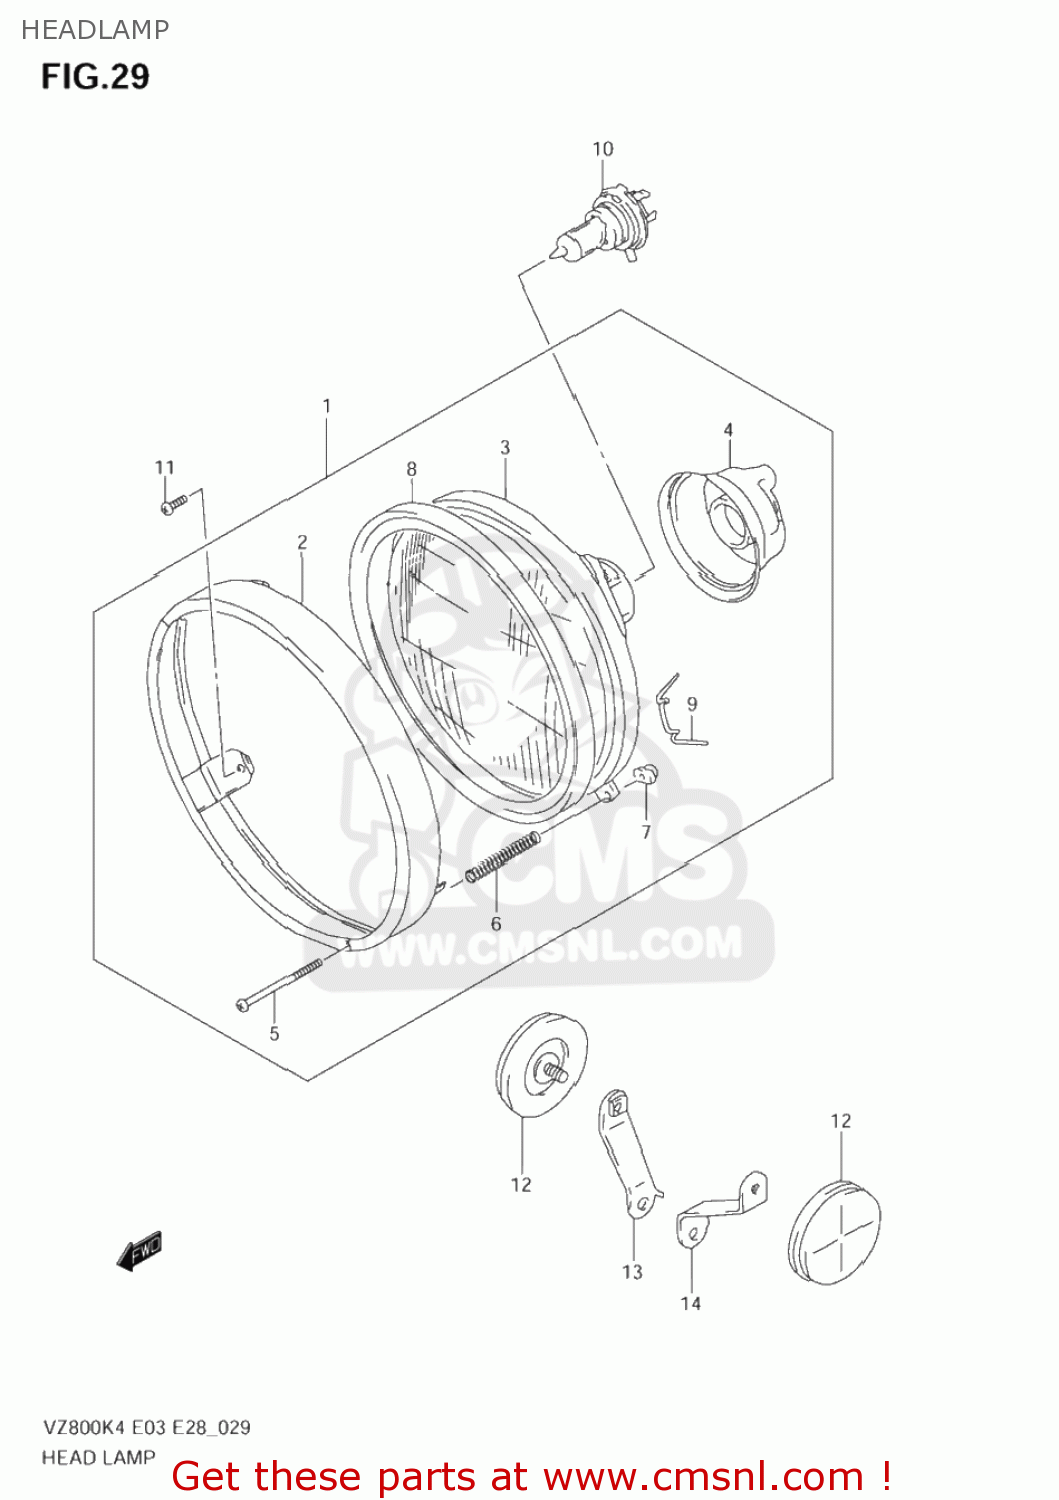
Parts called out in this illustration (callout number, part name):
1	HEADLAMP ASSY
2	RIM ASSY
3	LAMP UNIT
4	COVER,SOCKET
5	SCREW
6	SPRING,ADJUSTING
7	NUT
8	RING
9	SPRING
10	BULB(12V60/55W,H4)
11	SCREW(5X12)
12	REFLECTOR,REFLEX FR
13	BRACKET,FR SIDE RR,R
14	BRACKET,FR SIDE RR,L
